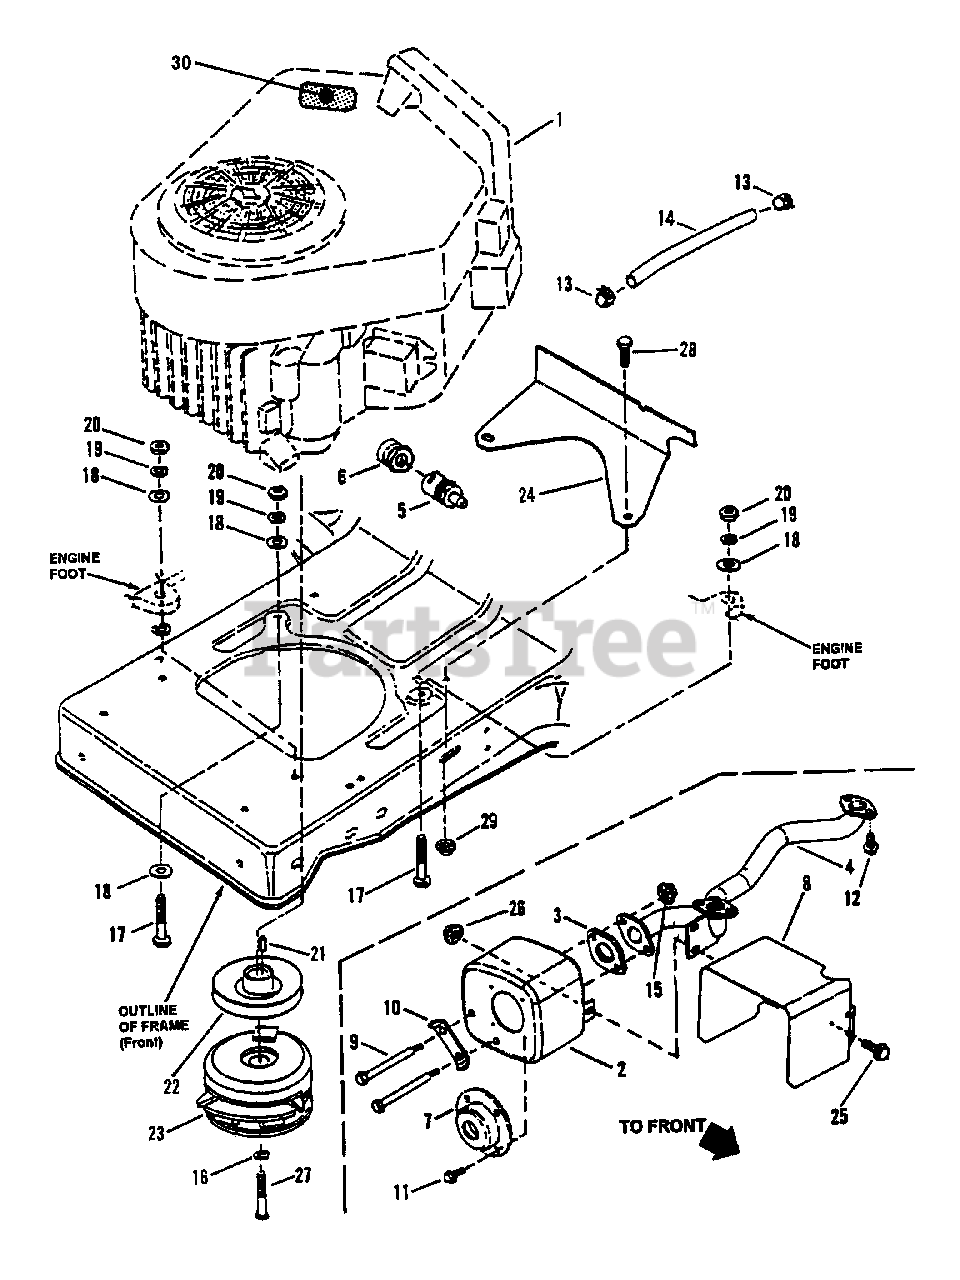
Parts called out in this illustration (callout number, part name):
2	MUFFLER
3	GASKET, Muffler/Exhaust
4	MANIFOLD, Exhaust
5	ASSEMBLY, Oil Valve Drain
6	EXTENSION, Oil Drain
7	DEFLECTOR, Exhaust
8	SHIELD, Muffler Heat
9	BOLT, 5/16-18 x 3-1/2" Shoulder, Hex Head
10	LOCK, Screw
11	SCREW, #8-18 x 1/2" Self-Tapping
12	SCREW, 5/16-18 x 1/2" Hex Washer Head, Self Tapping
13	CLAMP, Fuel Line
14	LINE, Fuel, 14" Long
15	NUT, 5/16-18 Hex Flanged Lock, Grade 5
16	WASHER, 7/16" Split Lock
17	SCREW, 5/16-18 x 1-3/4" Hex Head Cap, Grade 5
18	WASHER, 5/16 Flat Grade 5
19	WASHER, 5/16 Split Lock
20	NUT, 5/16-18 Hex Grade 5 or B
21	KEY, 1/4 x 1/4 x 3/4" Square
22	PULLEY, Traction Drive
23	CLUTCH/BRAKE
24	SHIELD, Heat
25	SCREW, 1/4-20 x 5/8" Hex Head Cap, Grade 5
26	NUT, 1/4 -20 Hex Flanged Lock, Grade 5
27	SCREW, 7/16-20 x 2-1/2 Hex Head Cap, Special, Grade 5
28	SCREW, 5/16-18 x 1" Hex Head Cap, Grade 2
29	NUT, 5/16-18 Hex Flange Lock, Grade 5
30	DECAL, Warning Speed Setting
